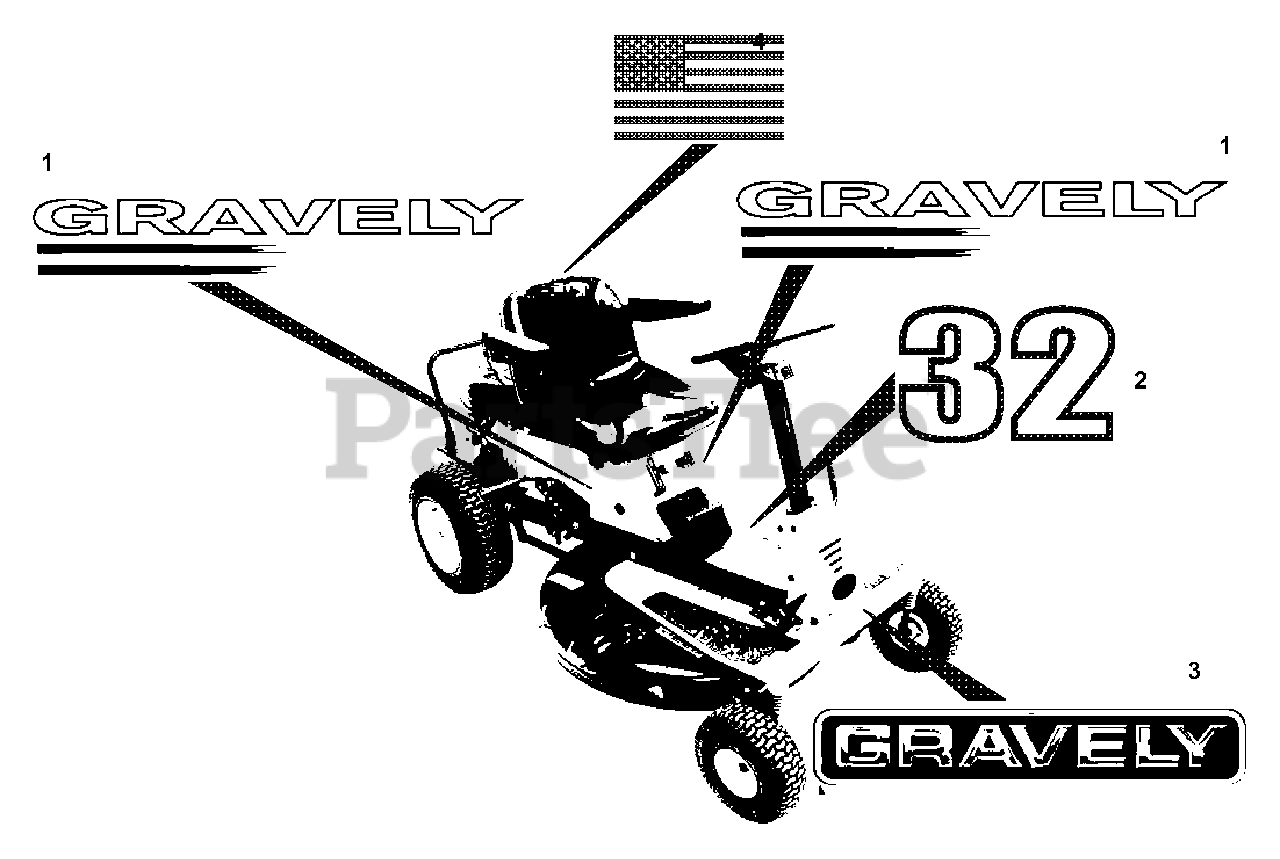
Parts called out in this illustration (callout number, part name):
1	Decal, Gravely ZT
2	Decal, 28 (066)
2	Decal, 32 (068)
3	Decal, Gravely
4	Decal, American Flag
